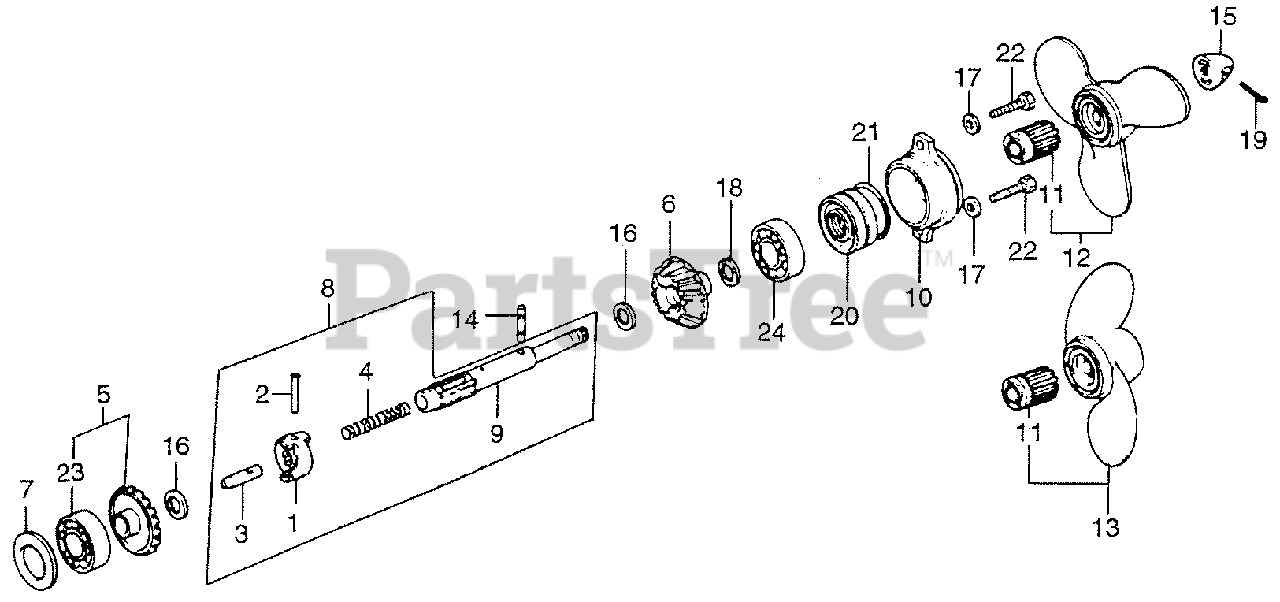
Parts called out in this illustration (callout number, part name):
1	SHIFTER, CLUTCH
2	PIN, SHIFTER (4X35)
3	SLIDER, SHIFT
4	SPRING, SHIFT
5	GEAR, FR. BEVEL
6	GEAR, RR. BEVEL
7	SHIM A, GEAR (0.10MM)
7	SHIM B, GEAR (0.15MM)
8	SHAFT, PROPELLER
9	SHAFT, PROPELLER
10	HOLDER, PROPELLER SHAFT *PB1* (DARK BLUE) (NOT AVAILABLE)
11	BUSHING, PROPELLER (NOT AVAILABLE)
12	PROPELLER, BLADE 3 *PB1* (DARK BLUE) (NOT AVAILABLE)
13	PROPELLER, BLADE 2 *PB1* (DARK BLUE)
14	PIN, SHEAR
15	CAP, PROPELLER (NOT AVAILABLE)
16	WASHER (17MM)
17	WASHER, PLAIN (6MM)
18	WASHER C, GEAR (2.10MM)
18	WASHER D, GEAR (2.15MM)
19	PIN, COTTER (3MM)
20	SEAL, WATER (17MM)
21	O-RING (62X2.5)
22	BOLT, HEX. (6X20)
23	BEARING, RADIAL BALL (6005)
24	BEARING, RADIAL BALL (6203)
